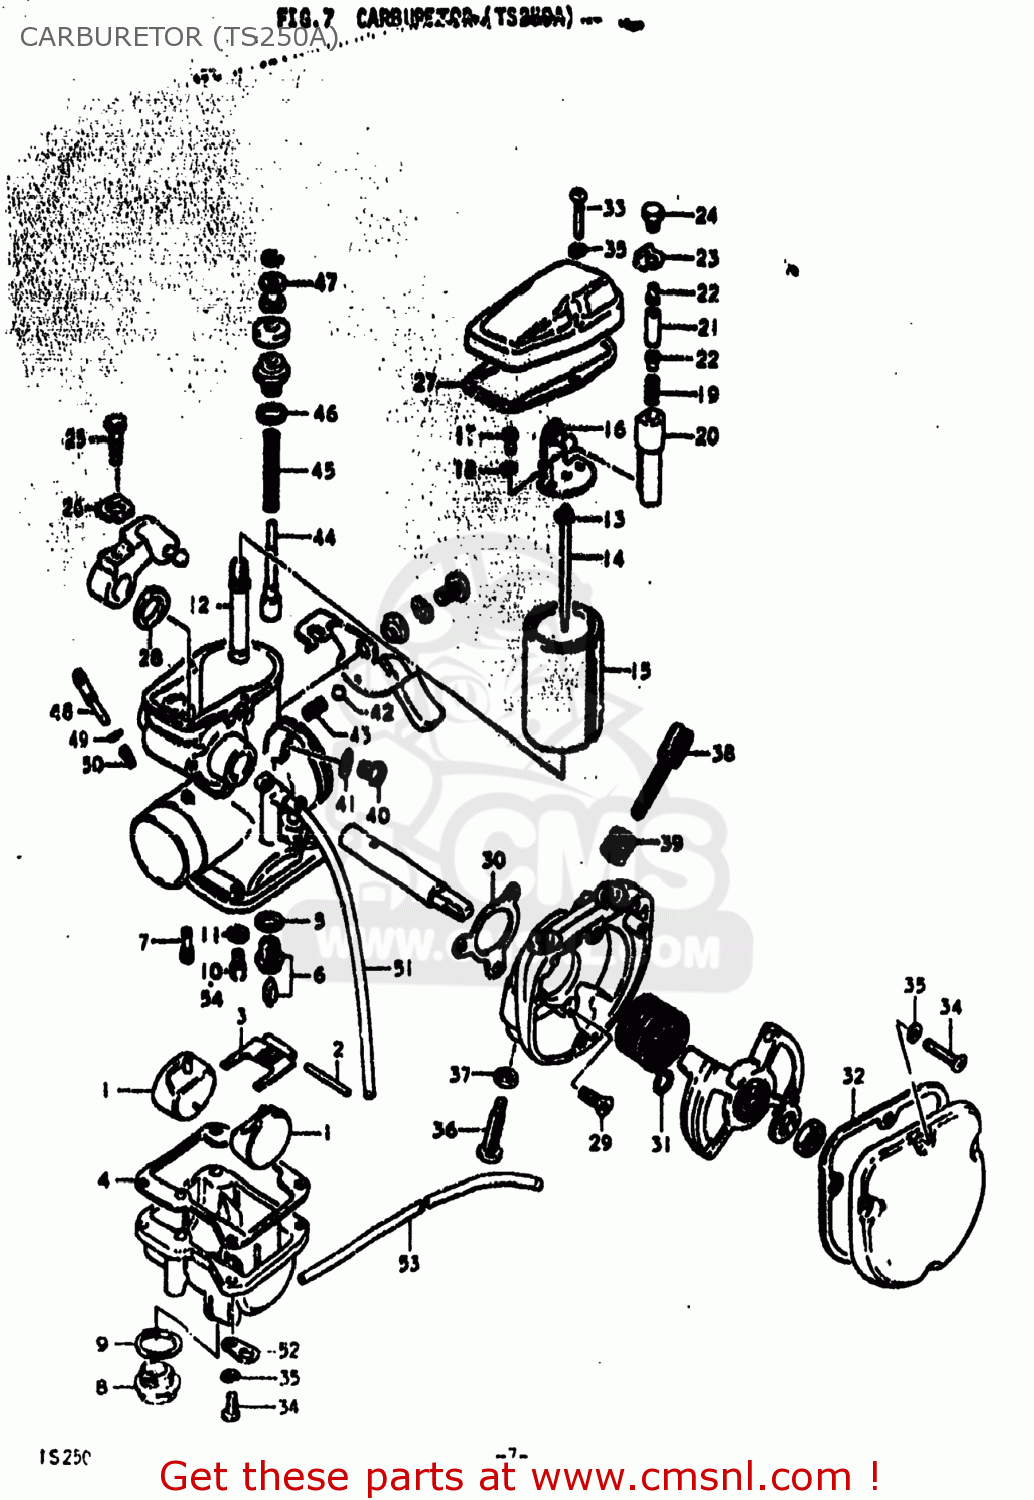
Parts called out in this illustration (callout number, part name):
1	FLOAT
2	PIN,FLOAT
3	ARM,FLOAT
4	GASKET,FLOAT CHAMBER
5	GASKET,VALVE SEAT (NAS)
6	VALVE ASSY,NEEDLE
7	JET
8	PLUG
9	GASKET,DRAIN PLUG (MCA)
10	JET,MAIN(160)
11	WASHER
12	JET,NEEDLE
13	CLIP
14	NEEDLE,JET(5CN3)
15	VALVE,THROTTLE
16	BRACKET,CARBURETOR
17	SCREW
18	LOCK WASHER
19	SPRING
20	LEVER ASSEMBLY
21	SPRING
22	PIN,CARBURETOR
23	PLATE,CARBURETOR
24	SCREW
25	BOLT
26	RING
27	GASKET,TOP (NAS)
28	RING
30	GASKET,CARBURETOR CASE
31	SPRING
32	GASKET,CARBURETOR CASE
33	SCREW
34	SCREW
35	LOCK WASHER
36	SCREW
37	NUT
38	SCREW,THROTTLE STOP
39	SPRING,THROTTLE SCREW
40	BOLT
41	GASKET,THRO VALVE INSPECTION (NAS)
42	BALL,STARTER SHAFT
43	SPRING,STARTER SHAFT
44	VALVE,STARTER
45	SPRING
46	O-RING
47	RING
48	SCREW,PILOT AIR ADJUSTING
49	O RING
50	SPRING
51	HOSE
52	PLATE
53	HOSE
54	JET
